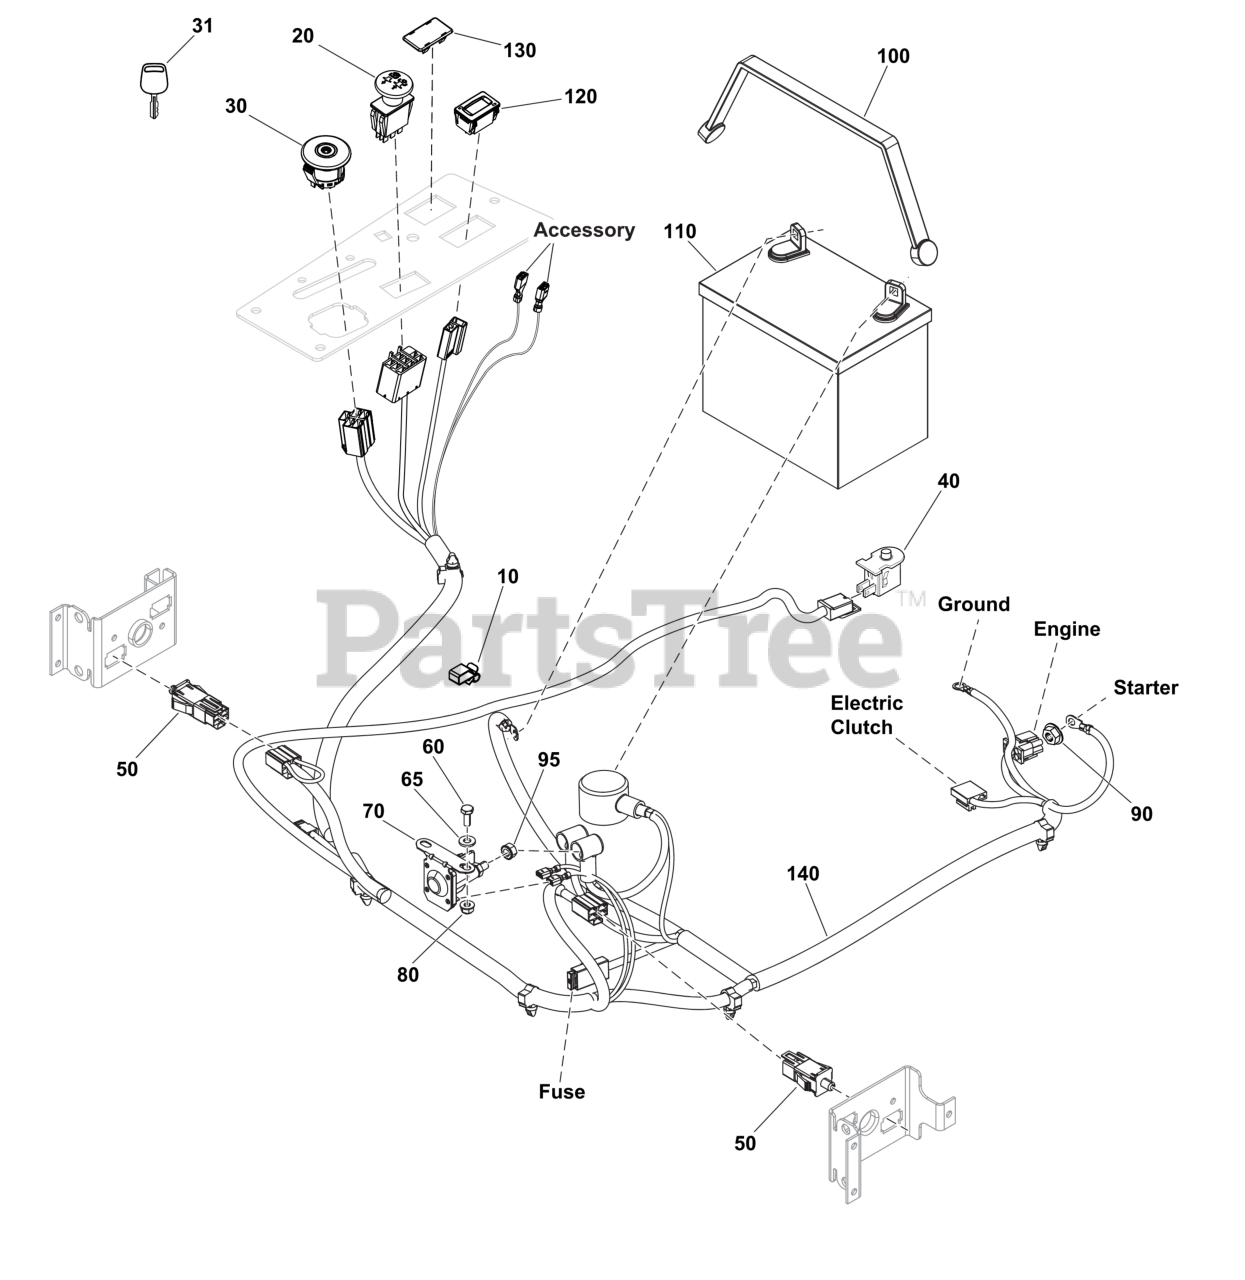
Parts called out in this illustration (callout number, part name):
10	CLIP- WIRE DIA .390
20	SWITCH-PTO PUSH
30	SWITCH, IGNITION, DEL
31	BLISTER PACK, KEY NO MOW & FOB
40	SWITCH, SEAT
50	SWITCH, DP NO/NC SNAP
60	BOLT,1/4-20X5/8
65	WASHER
70	SOLENOID, L-BRACKET
90	NUT, HEX KEPS, 1/4-20
95	NUT-HEX KEPS 5/16-24
100	STRAP
120	METER-HOUR DIGITAL NO
130	PLUG-HOLE BLACK
140	HARNESS, Wiring
